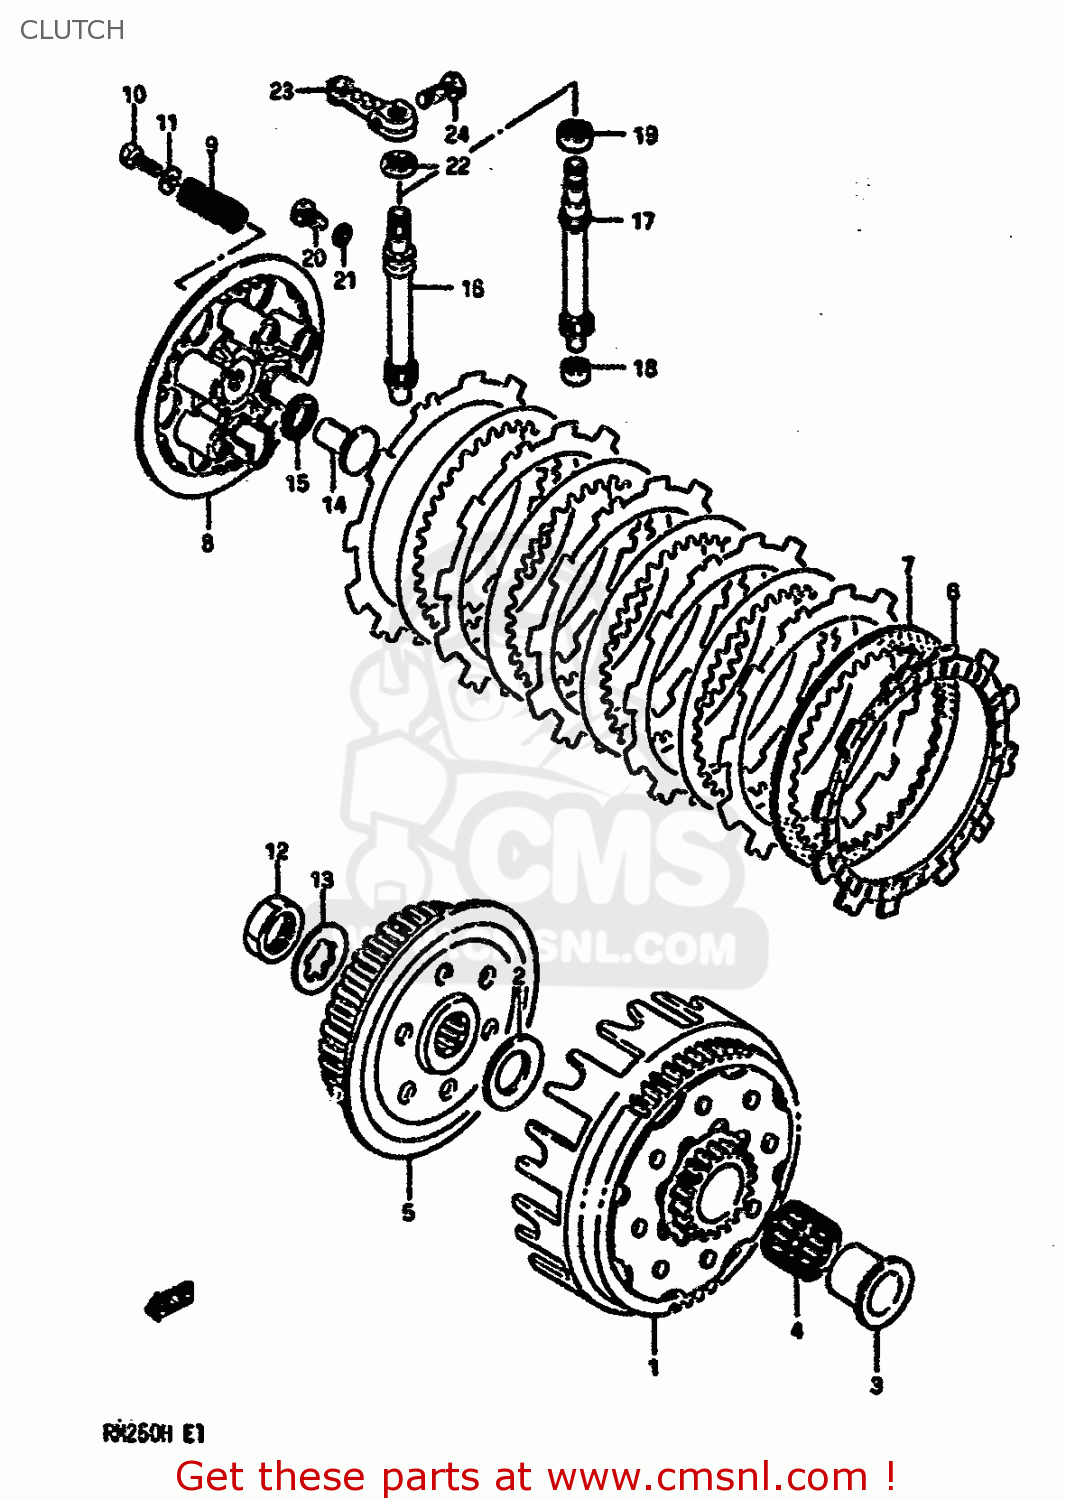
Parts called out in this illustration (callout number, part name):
1	GEAR ASSY,PRI DRIVEN
2	WASHER(20X36X2)
3	SPACER,PRIMARY DRIVEN
4	BEARING(25X30X22)
5	HUB,CLUTCH SLEEVE
6	PLATE,CLUTCH DRIVE
7	PLATE,CLUTCH DRIVEN (NAS)
8	DISC,CLUTCH PRESSURE
9	SPRING
10	BOLT(5X16)
11	WASHER (5.5X16X1.2)
12	NUT (20MM)
13	WASHER,LOCK
14	RACK,CLUTCH RELEASE
15	BEARING(10X22X2.8)
16	PINION,CLUTCH RELEASE
17	PINION,CLUTCH RELEASE(NT:12)
18	BEARING(9X13X10)
19	BEARING(12X16X10)
20	BOLT
21	GASKET(6.2X11X1).2 (NAS)
22	SEAL,OIL(10X17X5)
23	ARM,CLUTCH RELEASE
24	BOLT
